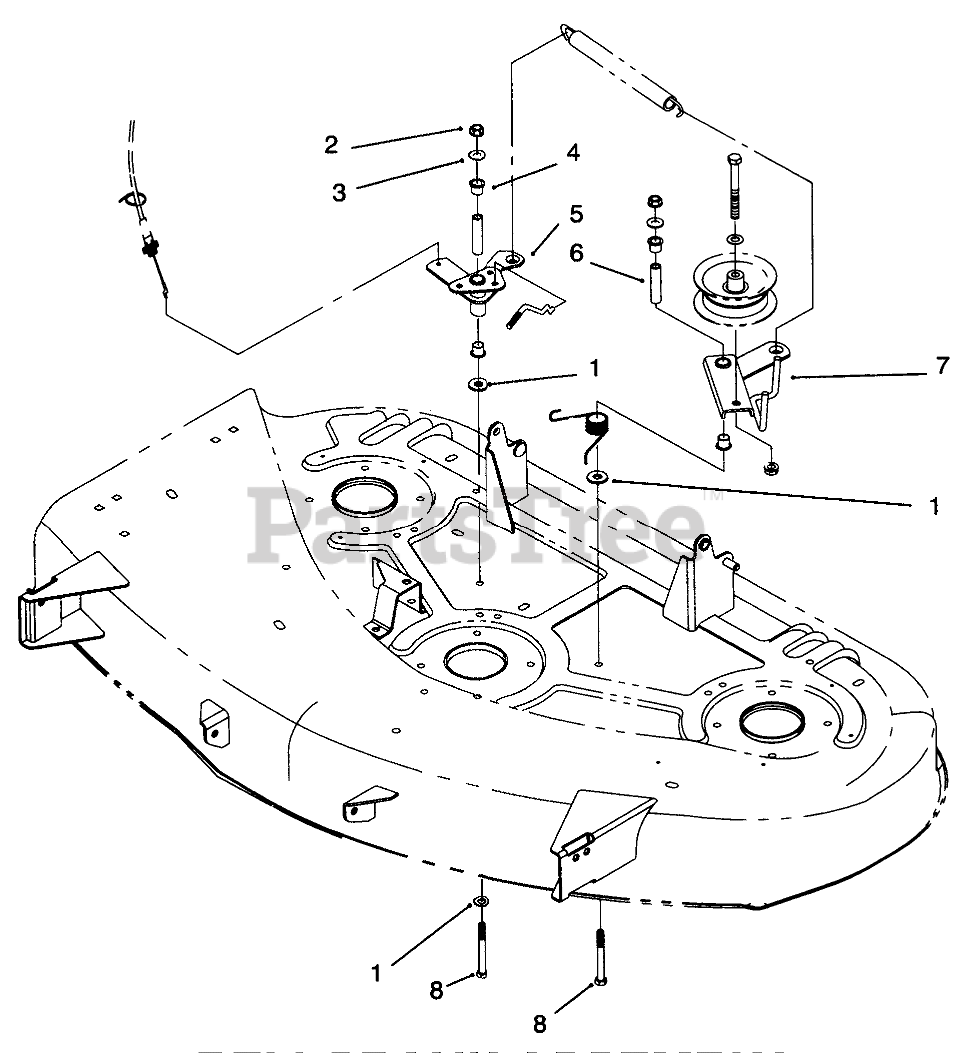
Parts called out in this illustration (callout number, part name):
1	WASHER-HARDENED
2	NUT-LOCK, NI
3	WASHER-FLAT
4	BUSHING-NYLINER
5	Bellcrank
6	SPACER-PIVOT
7	Bellcrank
8	SCREW-HH
